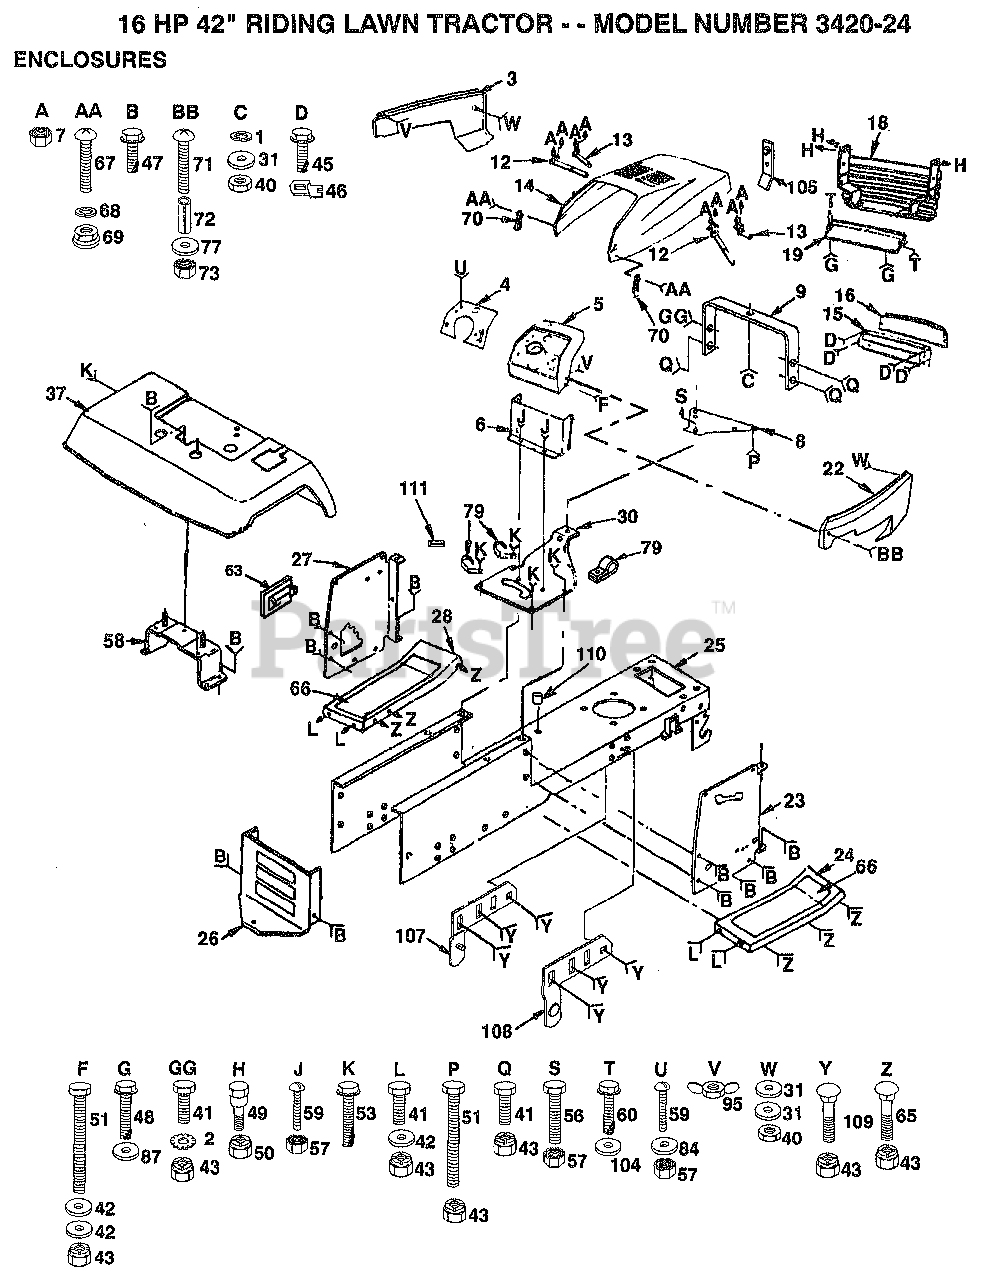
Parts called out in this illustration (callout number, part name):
1	LOCKWASHER
2	LOCKWASHER
3	"PANEL,SIDE LH"
6	DASH ASSY LT
7	NUT
9	SUPPORT ASS'Y
16	LENS LT
22	"PANEL,SIDE RH"
31	WASHER PM
42	WASHER
46	"""J"" FASTENER LT"
47	SCREW
48	SCREW
53	SCREW LT
56	BOLT
59	SCREW
60	SCREW HEX CRT
63	COVER ACCESS
65	BOLT
66	FOOTREST PAD
67	SCREW
68	LOCKWASHER
69	WELDNUT
70	HOOD LATCH T
71	SCREW
72	SPACER LT
77	WASHER
79	CLIP T
84	WASHER
87	WASHER
104	WASHER
107	PIVOT BRKT LH
108	PIVOT BRKT RH
109	BOLT
110	SNAP BUSHING T
